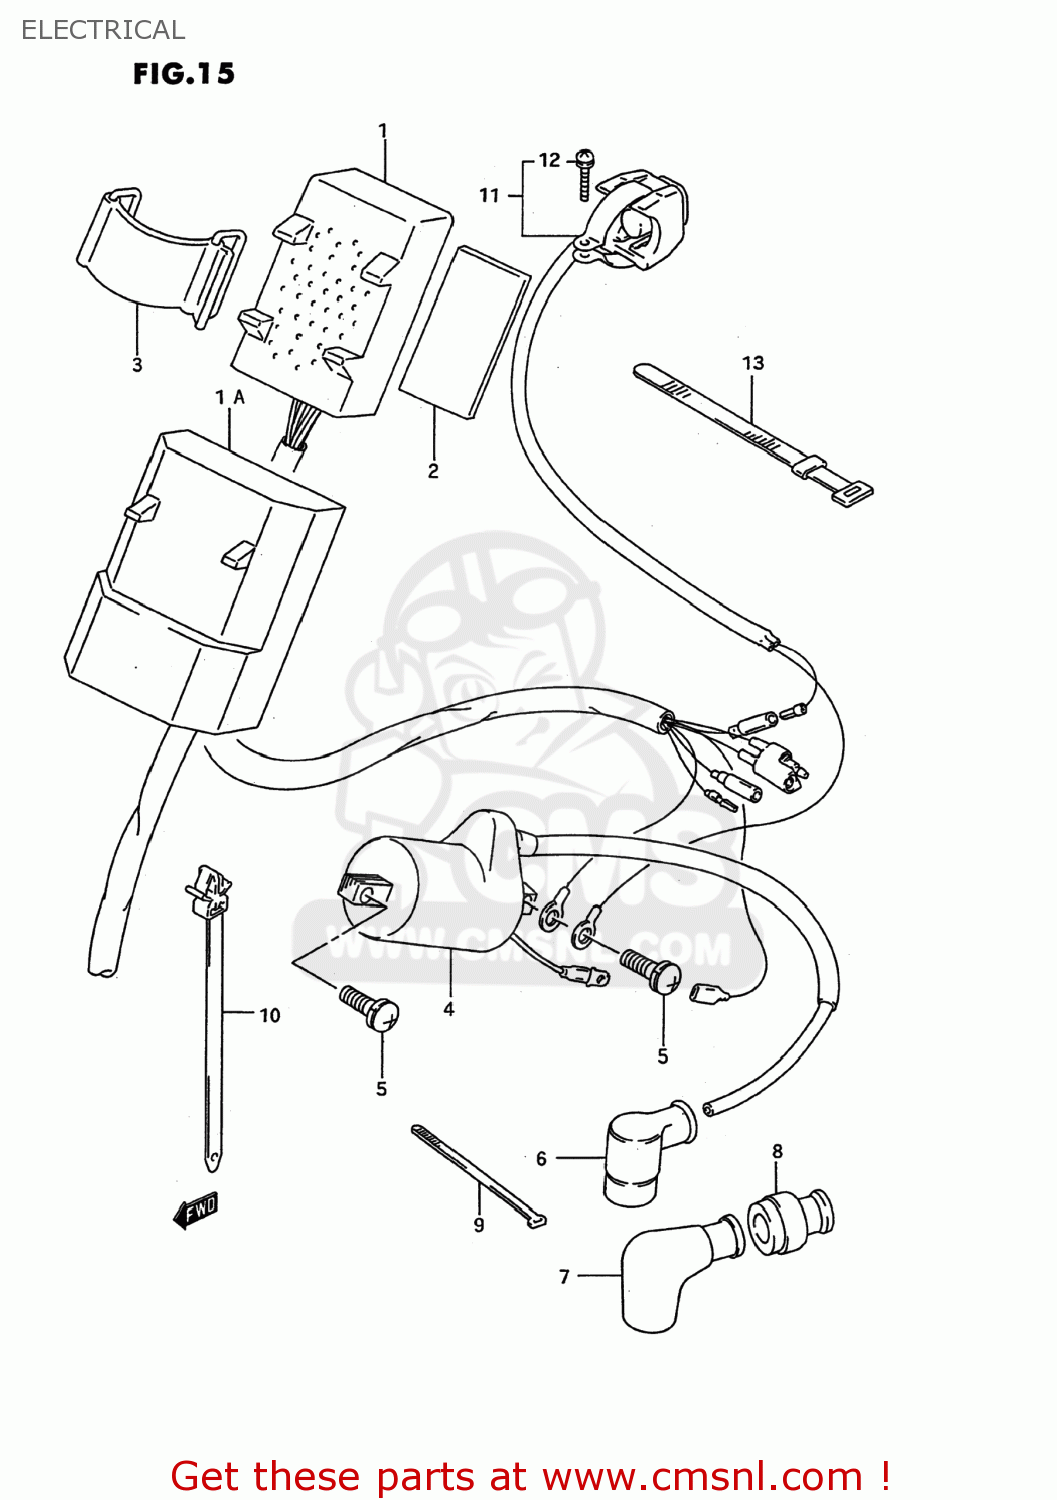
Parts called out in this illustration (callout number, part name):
1	CDI UNIT
1A	CDI UNIT
2	PROTECTOR(170X95X3.0)
3	BAND(L:65)
4	COIL ASSY,IGNITION
5	SCREW
6	CAP,SPARK PLUG
7	CAP,SPARK PLUG
8	SEAL,HIGH TENSION CORD
9	CLAMP
10	CLAMP(L:90)
11	SWITCH ASSEMBLY
12	SCREW
13	CLAMP(L:120)
